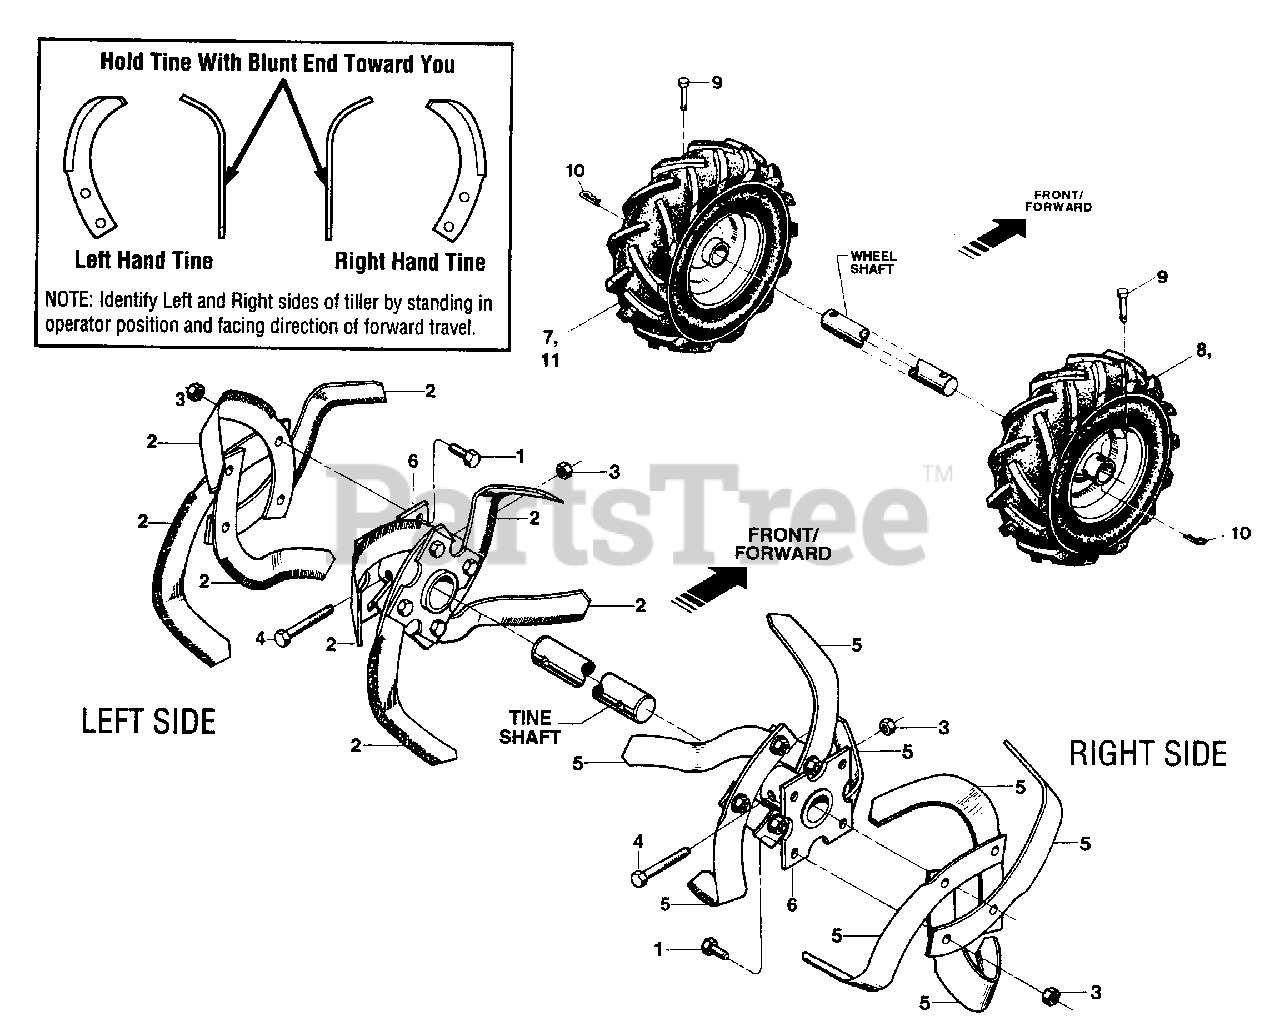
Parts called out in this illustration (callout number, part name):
1	Hex Screw, 3/8-16 x 1, Grade 5
2	Bolo Tine - Right Hand
3	Hex Locknut, 3/8-16
4	Hex Screw, 3/8-16 x 1-3/4
5	Bolo Tine - Left Hand
6	Tine Holder
7	Wheel & Tire Assy-Left Side
8	Wheel & Tire Assy-Right Side
9	Clevis Pin, .312" x 1-3/4"
10	Hair Pin Cotter
